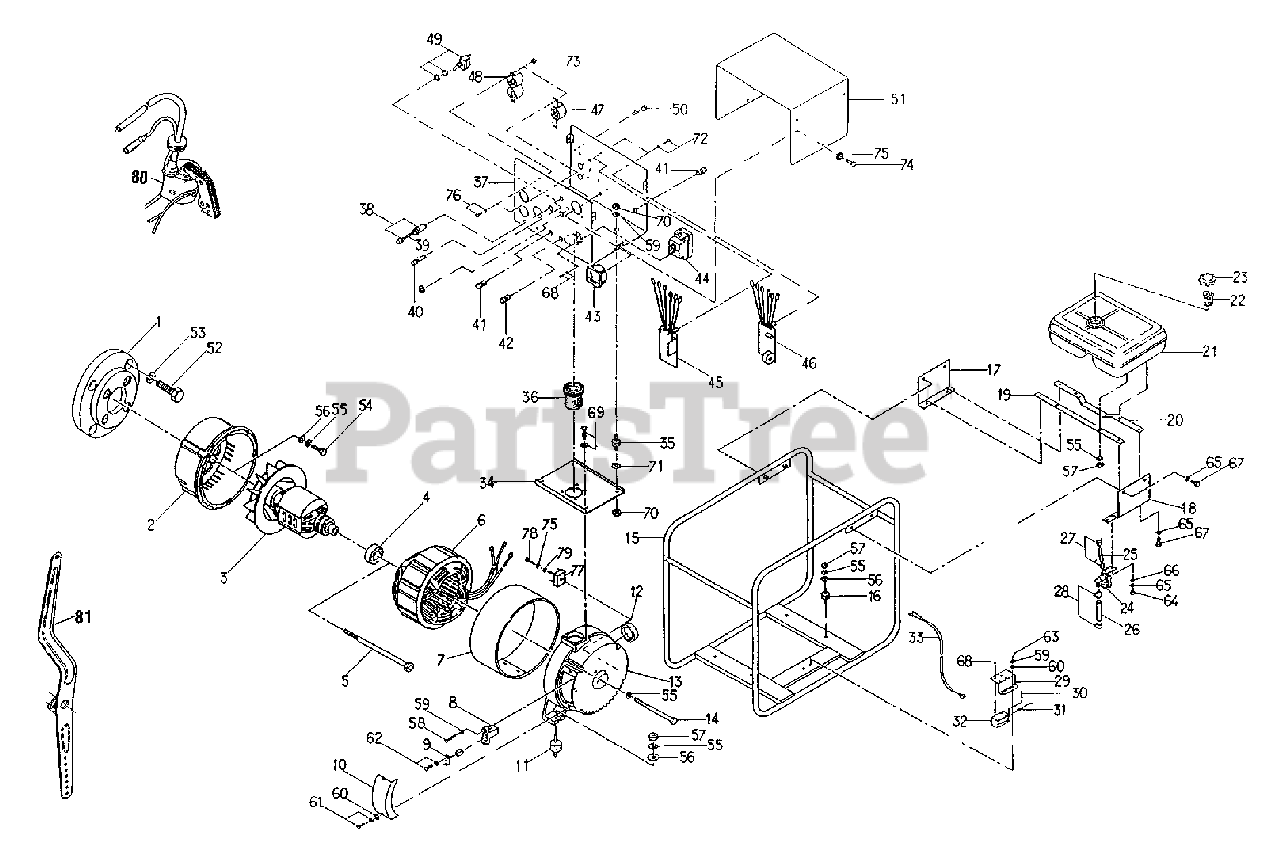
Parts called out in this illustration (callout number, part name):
1	FLANGE
2	BRACKET - FRONT
3	ROTOR ASSY
4	BEARING, BALL
5	THRU BOLT
6	STATOR ASSY
7	STATOR COVER
8	HOLDER, BRUSH
9	BRUSH UNIT
10	COVER, BRUSH
11	RUBBER MOUNT
12	CAP
13	BRACKET - REAR
14	BOLT, BRACKET
15	TUBE, FRAME
16	RUBBER MOUNT
17	BRACKET, TANK
18	BRACKET, TANK
19	BRACKET, FUEL TANK
20	BRACKET, FUEL TANK
21	FUEL TANK ASSY
22	FILTER, FUEL
23	CAP ASSY
24	STRAINER, FUEL
25	HOSE - RUBBER
26	HOSE - RUBBER
27	CLAMP, HOSE
28	CLAMP, HOSE
29	BRACKET, SOLENOID
30	PIN, SPLIT
31	SPRING
32	SOLENOID
33	WIRE ASSY
34	BOX BASE
35	RUBBER MOUNT
36	BUSHING
37	CONTROL BOX ASSY
38	HOLDER, FUSE
39	FUSE
40	NEON LAMP - 110V
41	OUTPUT TERMINAL - BLACK
42	OUTPUT TERMINAL - RED
43	METER - 150V
44	BREAKER - 30A
45	AVR UNIT
46	AUTOMATIC IDLE RETURN
47	OUTLET - 250V 15A
48	OUTLET - 125V 15A X 2
50	CORD BUSHING
51	BOX COVER
53	LOCKWASHER
54	BOLT - 8X20
55	LOCKWASHER - 8
56	WASHER - 8
57	NUT - 8
58	SCREW - 5X20
59	LOCKWASHER - 5
60	WASHER - 5
61	SCREW - 5X10 -- TAPPING
62	SCREW 4X6 -- TAPPING - BRASS
63	BOLT - 5X12
64	BOLT - 6X12
65	LOCKWASHER - 6
66	WASHER - 6
67	BOLT - 6X15
68	SCREW - 3X8 -- TAPPING
69	SCREW - 5X15 -- TAPPING
70	NUT - 5
71	LOCKWASHER - 5
72	SCREW - 4X6 -- TAPPING
73	NUT - 4
74	BOLT - 4X10
75	LOCKWASHER - 4
76	SCREW - 4X10 -- TAPPING
77	BLOCK, DIODE
78	SCREW - 4X18
79	WASHER - 4
80	IGNITION UNIT
81	LEVER, GOVERNOR
